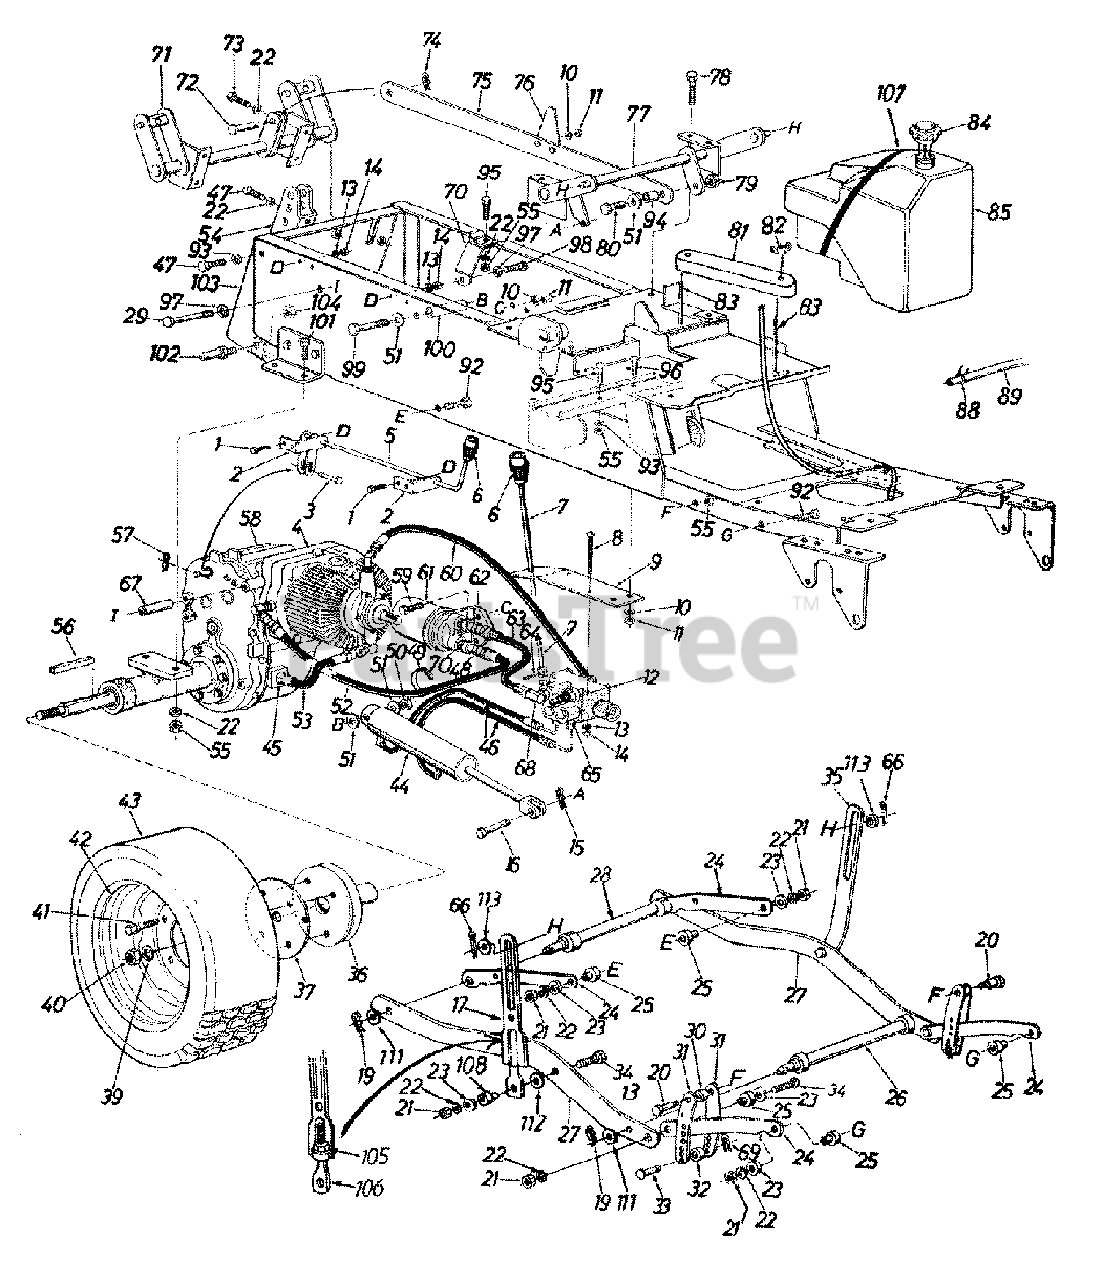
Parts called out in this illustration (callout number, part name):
1	Hex Bolt 1/4-20 x .75" Lg.
4	Hydrostatic Pump Comp.
5	Hi-Lo Control Handle Ass'y.
6	Shift Knob
7	Cylinder Control Handle Ass'y.
8	Truss Mach. Scr. 1/4-20 x 3.00" Lg.
11	Hex Nut 5/16-18 Thd.
12	Valve Ass'y. Comp.
13	L-Wash. 1/4" I.D.
14	Hex Nut 1/4-20 Thd.
15	Hairpin Cotter 1/2" Dia.
16	Clevis Pin 1/2" Dia.
17	Adj. Deck Link
19	Hairpin Cotter
20	Shld. Bolt .498" Dia. x .66"
21	Hex Nut 3/8-24 Thd.
22	L-Wash. 3/8" I.D. - H.D.
23	Fl-Wash. .38" I.D. x 1.00"
26	Cross Shaft Ass'y. - Front
29	Hex Bolt 1/2-13 x 2.75"
30	Collar .50" I.D. x 1.0"
33	Clevis Pin 3/8" Dia.
34	Hex Bolt 3/8-24 x 1.50" Lg.
40	Hex Ins. L-Nut 3/4-16 Thd.
41	Wheel Lug Bolt
44	Hydraulic Cylinder
45	7/8-14 UNF-2A Thd. 5/8 Tube Fitting
46	Valve to Cylinder Hose - 20"
47	Hex Bolt 3/8-16 x .75" Lg. - Grade 5
48	Bushing Reducer
49	Cable Tie
50	Hex Jam Nut 1/2-20 Thd.
51	Fl-Wash. .50" I.D. x 1.25
52	Filter Return Hose 24" Lg.
53	Pump Tube Ass'y.
55	Hex Nut 3/8-16 Thd.
56	Sq. Key 1/4" x 1/4" x 2"
57	Hairpin Cotter 1/4" Dia.
58	Peerless Transaxle
59	Hex Bolt 5/16-18 x 1.25"
60	Pump to Valve Hose
61	Fram Filter Ass'y. PH-16
63	Valve to Filter Hose - 8.38"
64	Spring Pin Spiral 1/8" Dia.
65	Flare Adapter
66	Cotter Pin 1/8" Dia. x 1.0"
68	Adapter 9/16-18 to 9/16-18
69	Hairpin Cotter
70	Transmission Brace
73	Hex Scr. 3/8-16 x 1.00" Lg. Grade 5
74	Cotter Pin 1/8" Dia. x 1.25"
79	Hex Cent. L-Nut 1/2-20 Thd.
80	Hex Scr. 1/2-20 x 1.25" Lg.
81	Battery Cover
82	Wing Nut 1/4-20 Thd.
83	Battery Hold Down Rods
84	Gas Tank Cap
85	Gas Tank Ass'y.
88	Gas Line Clamp 1/2"
89	Gas Line 20" Lg.
92	Hex Scr. 3/8-24 x 1.50" Lg.
93	L-Wash. 3/8" Scr.
94	Push Bar Sleeve
95	Hex Scr. 3/8-16 x 1.00" Lg.
96	Hex Scr. 5/16-18 x .75" Lg.
97	L-Wash. 1/2" Scr.
98	Hex Scr. 1/2-13 x 1.25" Lg.
99	Hex Scr. 1/2-20 x 3 1/2" Lg. - Grade
100	Spacer for Cylinder
101	Hex Scr. 3/8-16 x 1.75" Lg.
102	Link Clevis Pin
105	Hex Nut 1/2-13 Thd.
106	Eye Bolt
108	Spacer .385" I.D.
111	Fl-Wash. .63" I.D. x .93" O.D.
112	Fl-Wash. .381" I.D. x .87" O.D.
113	Fl-Wash. .5" I.D. x 1" O.D.
